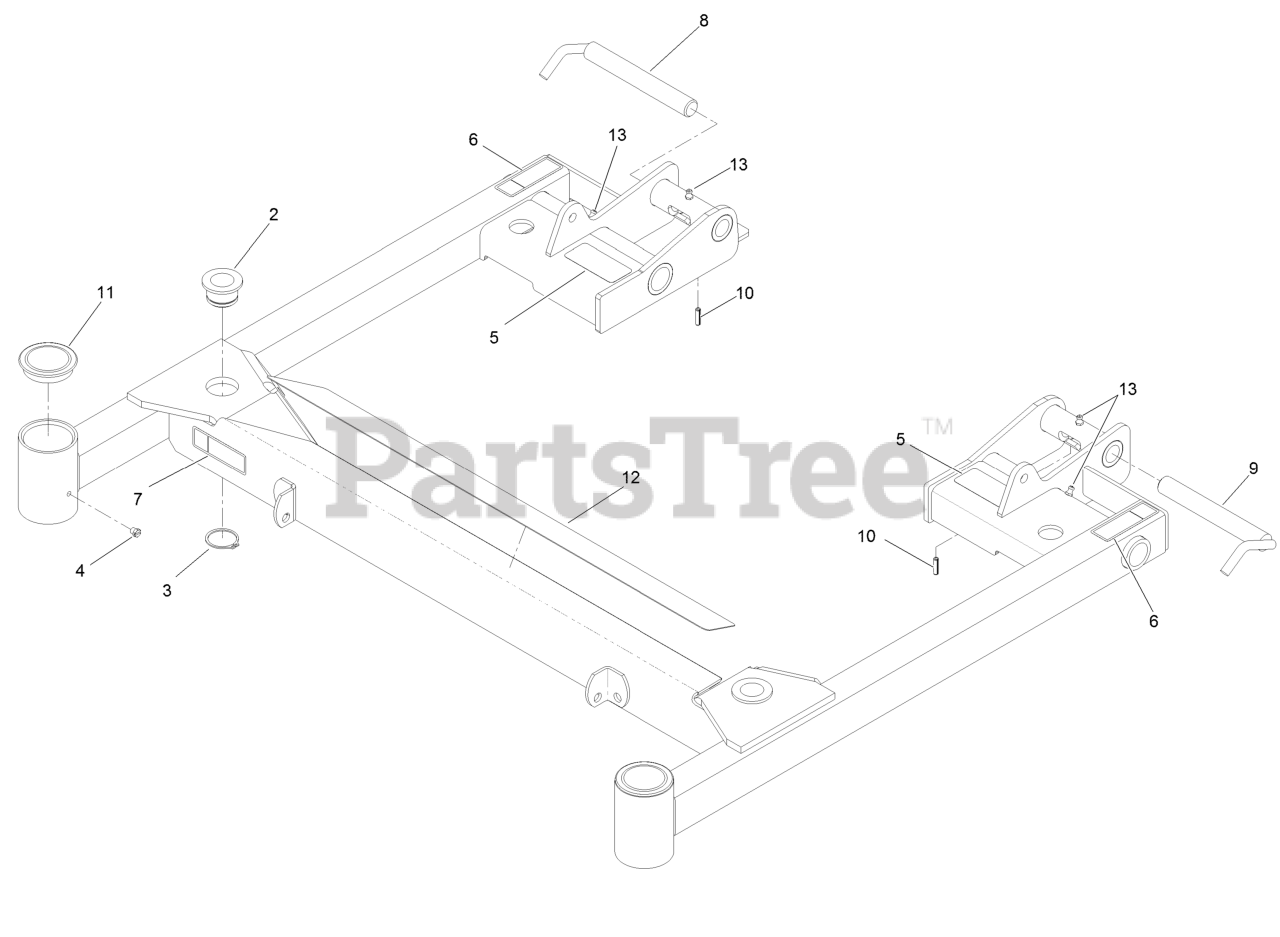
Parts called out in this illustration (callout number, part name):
2	Bushing-Support, Deck
3	Ring-Retaining
5	Decal-Warning
6	Decal-Warning, Folding Deck
7	Decal-Danger
8	Lock-Deck, RH
9	Lock-Deck, LH
10	Pin-Spring
11	Cap-Grease
12	Pad-Anti Skid
13	Fitting-Grease
